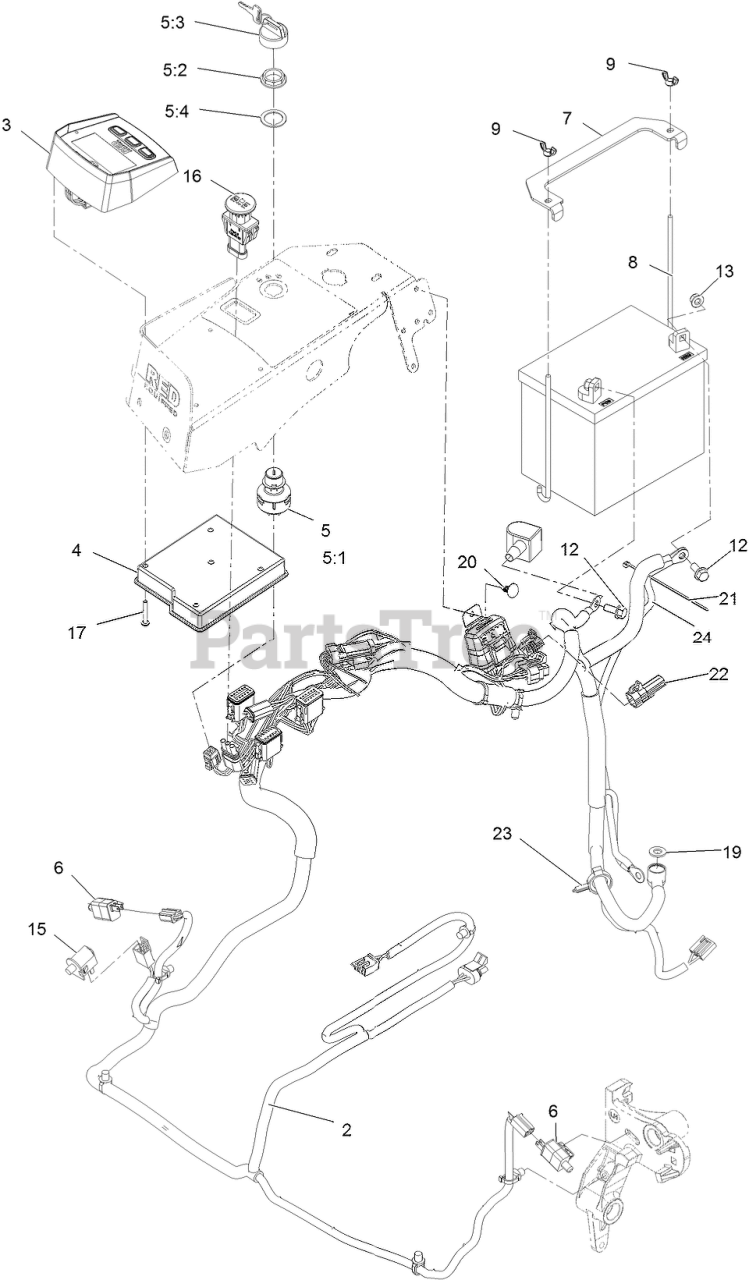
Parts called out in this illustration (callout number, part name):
2	HARNESS-WIRE
3	MODULE, LDU
4	Module-Mcu
5	IGNITION SWITCH ASM
5:1	Switch-Ignition
5:2	NUT-MOUNTING
5:3	IGNITION KEY SET
5:4	WASHER-BACKUP
7	STRAP-TIE DOWN, BATTERY
8	BOLT-HOLDDOWN
9	WINGNUT
12	SCREW-HHF
13	NUT-HF, NI
15	SWITCH-BAIL
16	SWITCH-PTO, SEALED
17	SCREW-PPH
19	WASHER-FLAT
20	PLUG-PLASTIC
21	TIE-CABLE
22	COVER-CONNECTOR, MP150, 4M
23	CLAMP-HOSE
24	CABLE-BATTERY, BLACK
